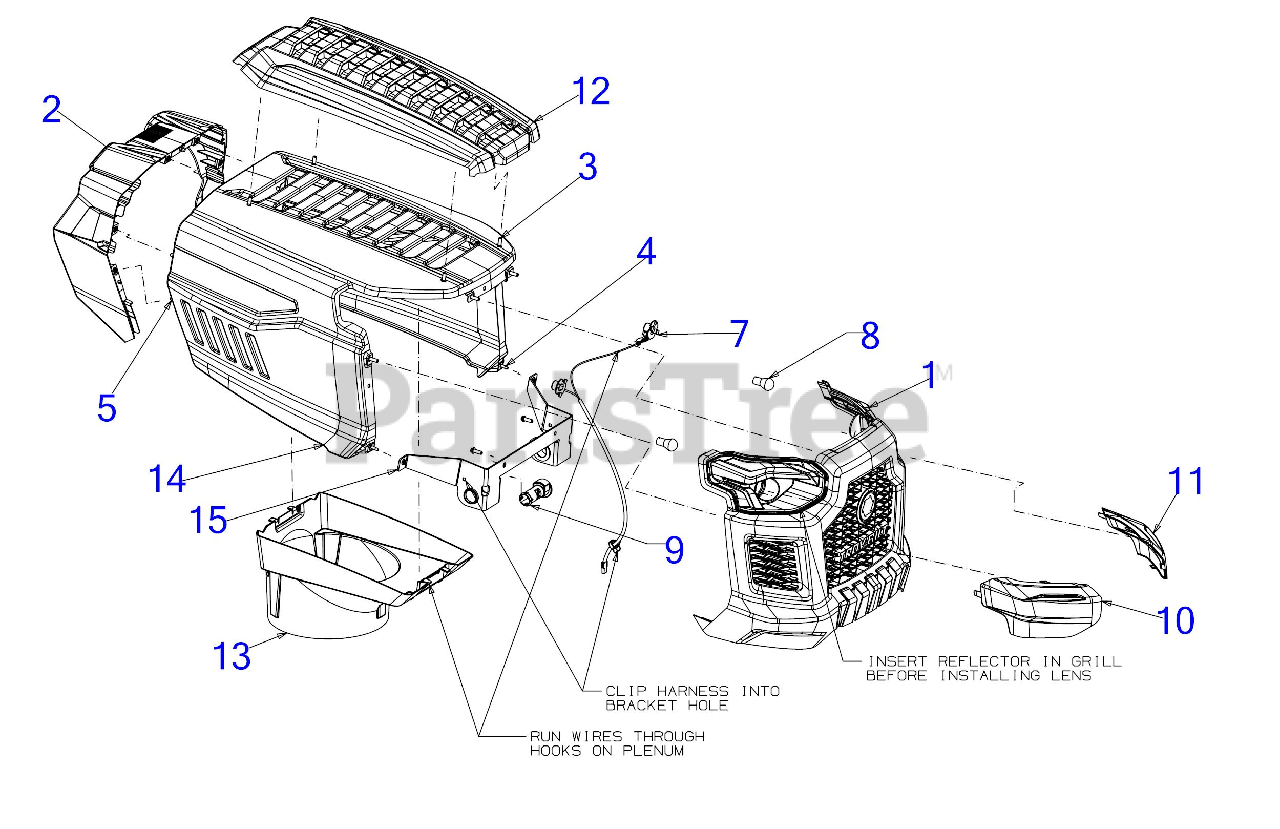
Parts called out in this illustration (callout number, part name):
1	FRONT GRILLE
3	SCREW 1/4 x .750
4	SCREW M6-1 x .625
5	SCREW 1/4-20X.5 GR5
7	HEADLIGHT HARNESS
8	MINIATUURE BULB 12V
9	HOOD PIVOT PIN
10	HEADLIGHT LENS (RH)
11	HEADLIGHT LENS (LH)
12	HOOD SCOOP
13	HOOD PLENUM (B STYLE)
